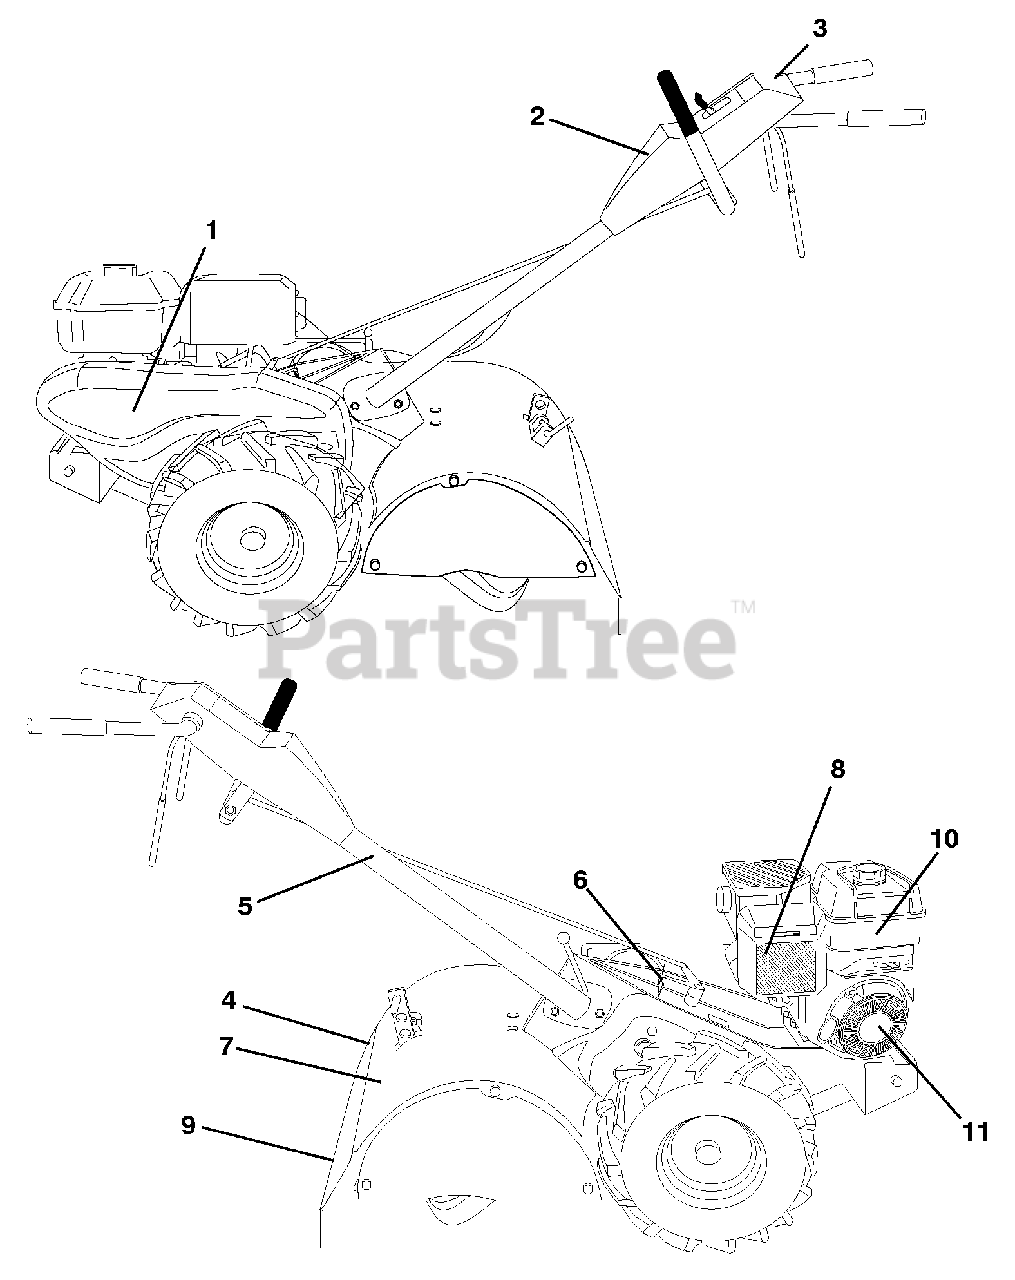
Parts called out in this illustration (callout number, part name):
1	Decal, Belt Guard Badge
2	Decal, Husqvarna, Control Panel
3	Decal, Control Tine
4	Decal, Tine Shield
5	Decal, Hand Placement
6	Decal, Shift Indicator
7	Decal, Warning
8	Decal, Engine, 8.5
9	Decal, Warning, Rotating Tines
10	Decal, Engine, Fuel Tank, 8.5
11	Decal, Rewind Starter, B & S
